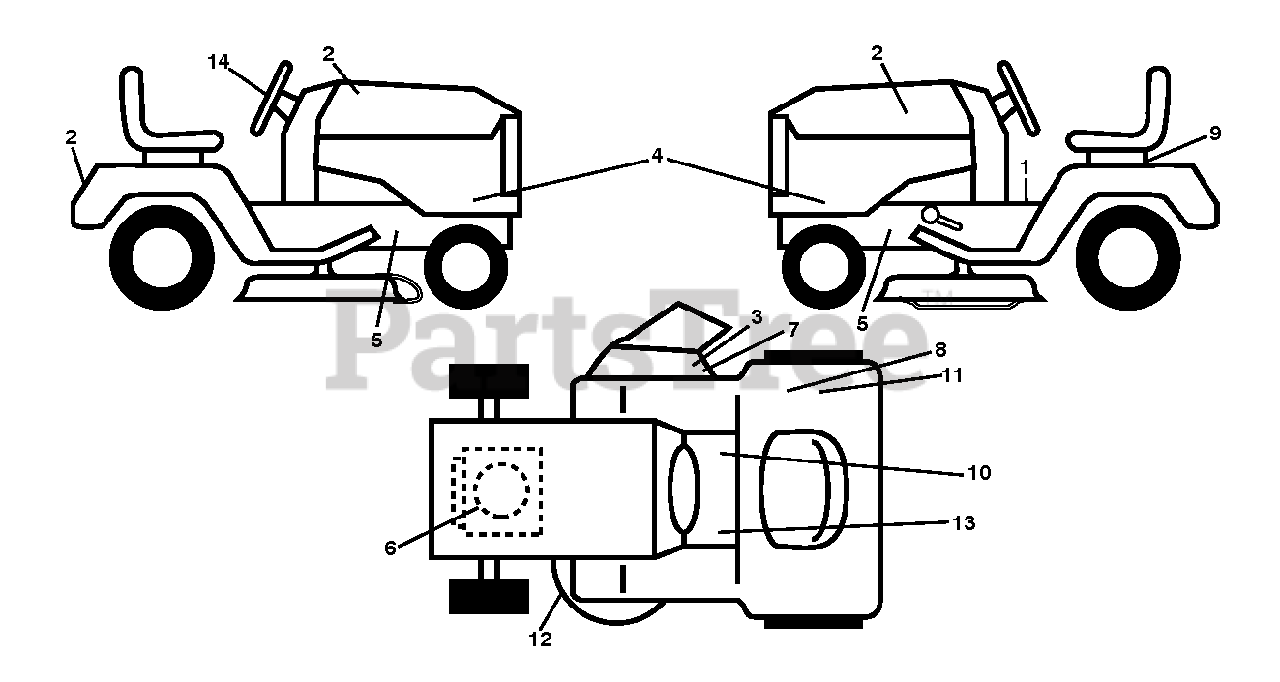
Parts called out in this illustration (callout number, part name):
1	DECAL.READ.OWN.MAN.SYMBOL.LT
2	DECAL, DIXON LOGO, DOMED
4	DECAL.LTPRED.SDPNL.19/42.KOHLE
5	DECAL.CHASSIS.HOT.MUFFLER
6	DECAL.ENGINE.WARNING
7	DECAL.DFLCTR.WARNNG.CTFNGR.SYM
8	DECAL.80.DBA.AUSTRALIA
9	DECAL BTRY SYMBOLS
10	DECAL.PARKING.BRAKE.SADDLE.LT
11	DECAL.TICKMARK.6MIL.AUSTRALIA
12	DECAL.V-BELT.SCH.42/46"MEC/ELE
13	DECAL.FNDR.SDLE.BRAKE.CLUTCH.6
14	DECAL.WHEEL.STEER.DIXON
